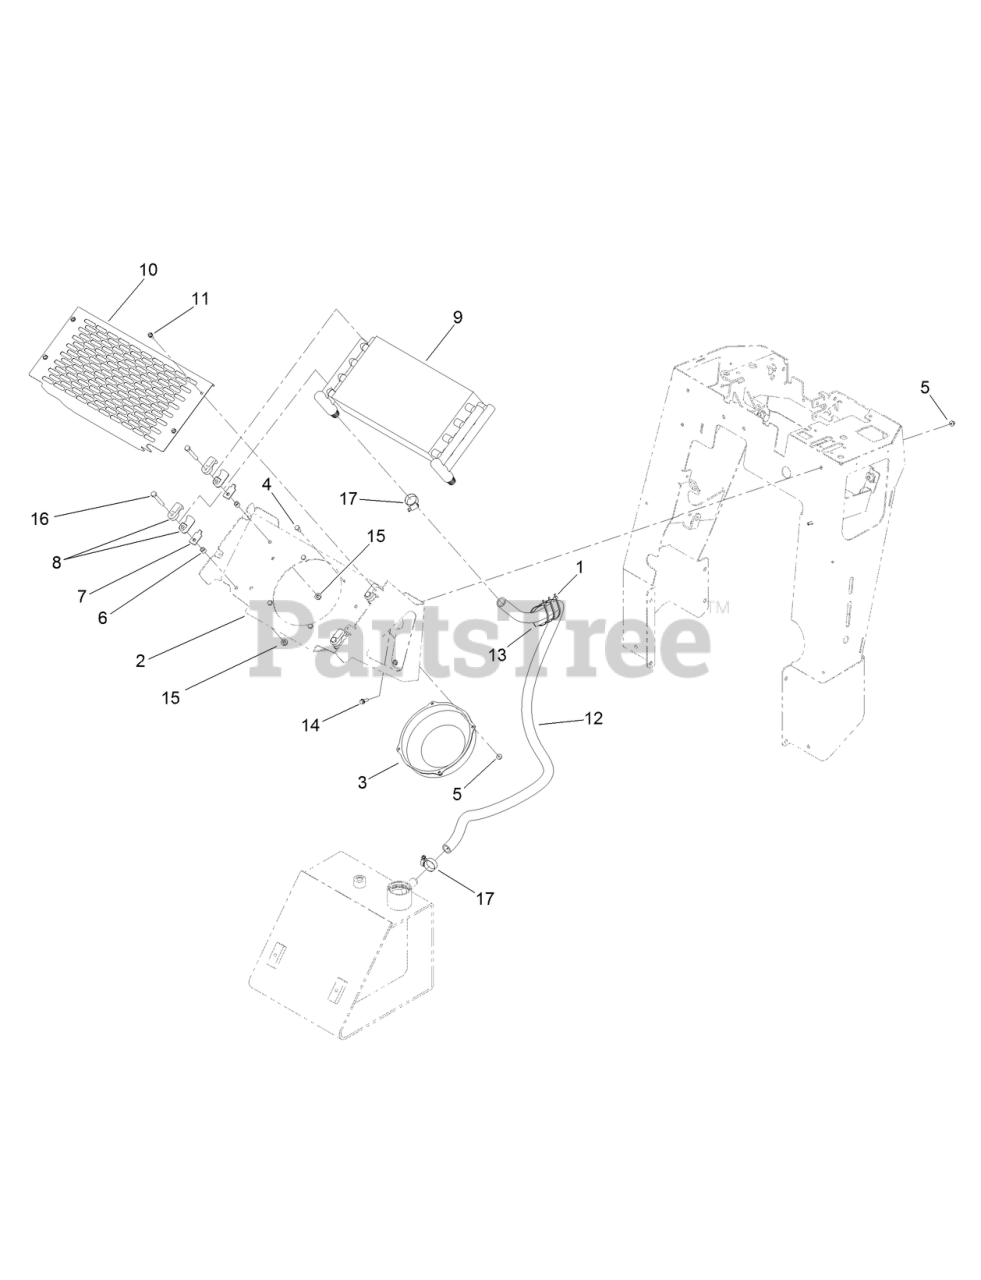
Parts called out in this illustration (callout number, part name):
1	TIE-CABLE
2	MOUNT-COOLER
4	SCREW-HH
5	NUT-HF
6	Spacer-Tube
7	PLATE-SUPPORT, CLAMP
9	COOLER-OIL
10	COVER-COOLER
11	SCREW-HWH
12	HOSE-COOLER
13	PROTECTOR-HOSE
14	SCREW-HHF
15	NUT-HF, NI
16	SCREW-HH
17	CLAMP-HOSE
